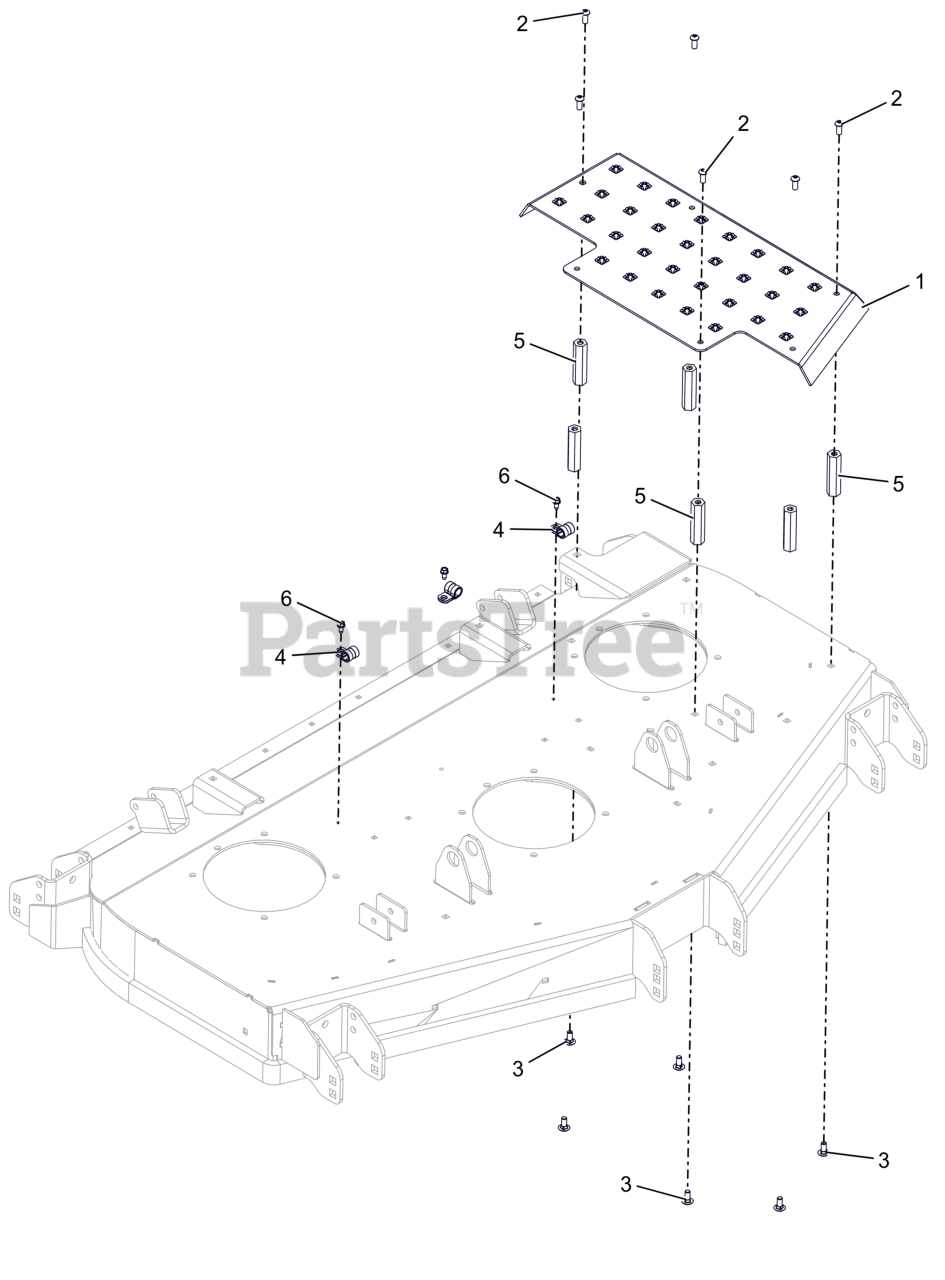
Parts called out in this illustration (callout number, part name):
1	PLATFORM, WLDMT 52 RD DECK STEP (ORANGE)
2	SCR-SKH .31-18X.75 BTNHD YWZC
3	BLT, RHSN .31-18X.75 G5 ZCC LT
4	CLAMP, CUSHIONED STEEL
5	NUT, COUPLING .31-18 X 3.00
6	SCR-TAP .25-20X.50 HWH ZCC
